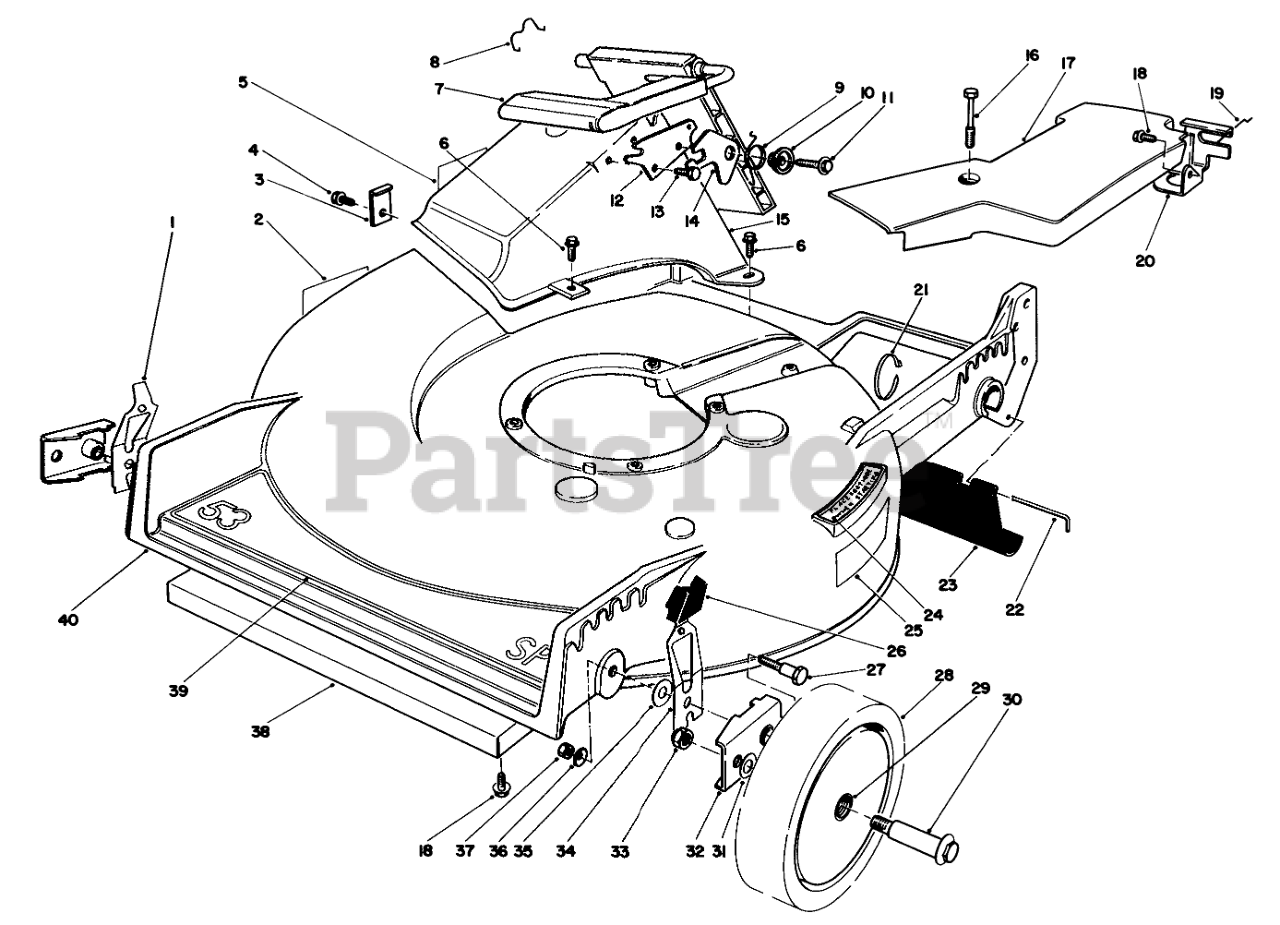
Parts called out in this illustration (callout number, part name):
1	R HP SPRING ARM ASM
2	Decal Danger
3	TUNNEL CLIP
4	SCREW
5	DECAL - DANGER
6	SCREW-HWH
7	Discharge Door Assembly
8	DOOR RET SPRING
9	TORSION SPRING
10	DOOR SPACER
11	SCREW-HWH
12	DOOR LATCH PLATE
13	SCREW-PLASTITE
14	SAFETY LATCH
15	Tunnel Discharge
16	SCREW-HHFTF
17	Cover-Belt
18	SCREW-HWHTF
19	RETAINER-CABLE
20	Bracket-Traction Adj.
21	TIE-CABLE
22	ROD-SHIELD
23	SHIELD-TRAILING
24	DECAL - STEP PAD INT'L
25	Decal Danger
26	KNOB-ARM
27	PIVOT SCREW
28	Wheel & Tire Assembly (Incl. Ref. #29)
29	BUSHING
30	BOLT-WHEEL
31	WASHER
32	HP PIVOT ARM ASM
33	Nut
34	L. HP SPRING ARM ASM
35	WASHER-PIVOT
36	WASHER-BELLEVILLE
37	NUT-LOCK, NI
38	Shield-front
39	DECAL - 53 SP DECK
40	21" Housing
